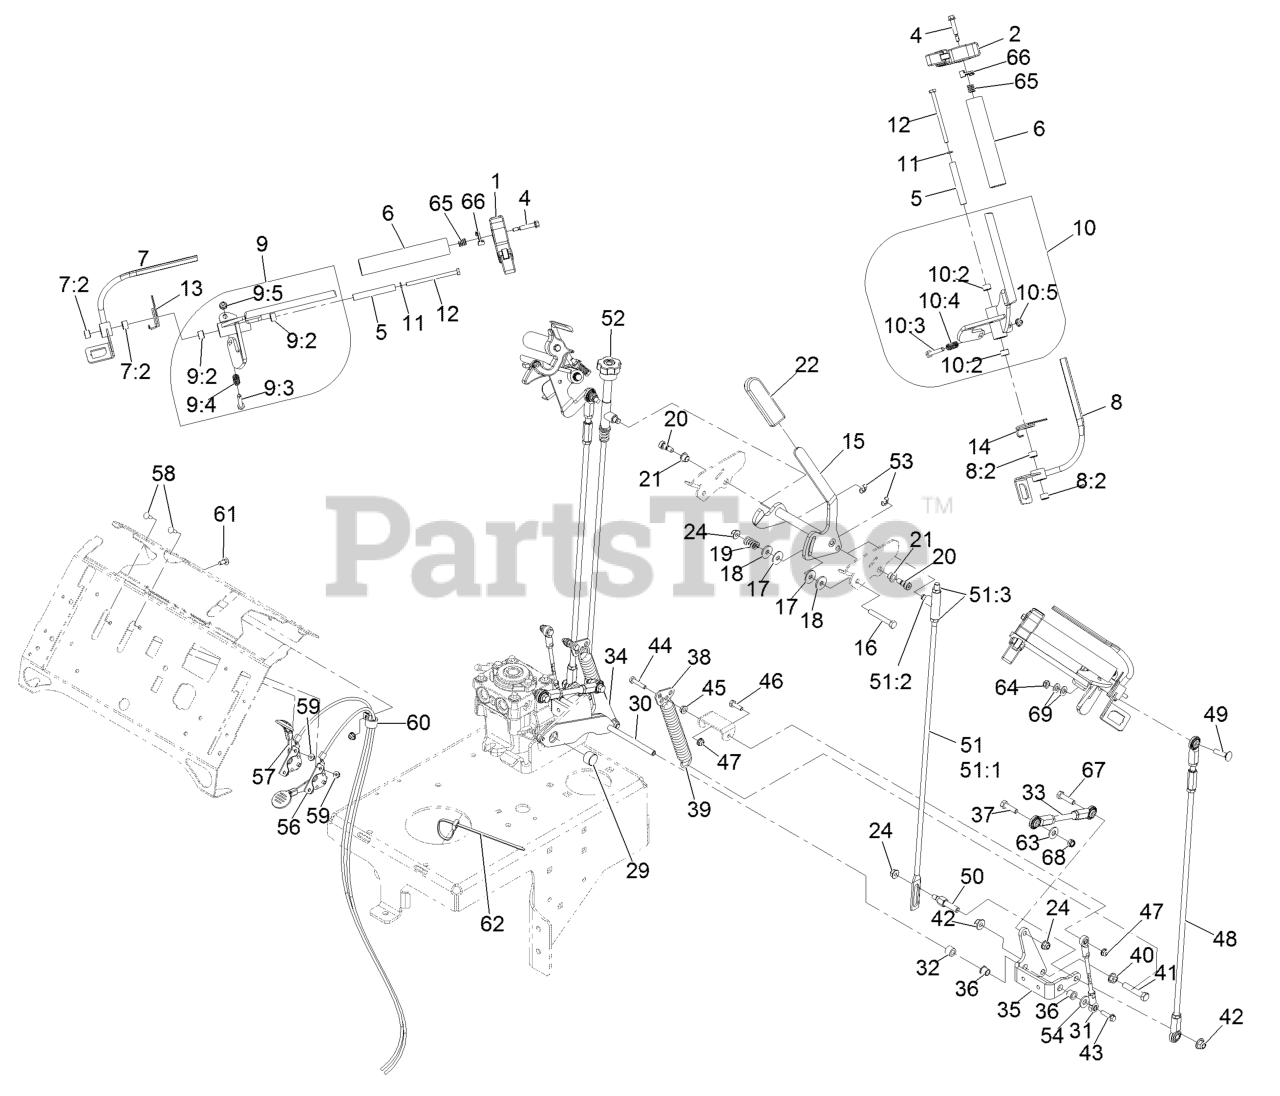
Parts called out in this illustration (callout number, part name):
1	ASM,LATCH RH THUMB
2	ASM,LATCH LH THUMB
4	SCREW-SHOULDER
6	GRIP-BAR, HANDLE
7	OPC-W/BUSHING, RH
7:2	BUSHING-SLEEVE
8	OPC-W/BUSHING, LH
8:2	BUSHING-SLEEVE
9	ASM, RT DRIVE LEVER
9:2	BUSHING-SLEEVE
9:3	SCREW-HH
9:4	SPRING, COMPRESSION
10	ASM, LT DRIVE LEVER
10:	BUSHING-SLEEVE
10:	SCREW-HH
10:	SPRING, COMPRESSION
11	SCREW-HH
12	SCREW-HH
13	SPRING, TORSION
14	SPRING, TORSION
15	SPEED CONTROL ASM
16	SCREW-HH
17	WASHER-FRICTION
18	WASHER-FRICTION
19	SPRING-COMPRESSION
20	SCREW-HSH
21	BUSHING
22	GRIP-HANDLE, STEERING
24	NUT-HF, NI
29	PIN-BELLCRANK LINK RETAIN
30	BELLCRANK LINK ASM
31	ASM, LINK
32	SPACER-WHEEL
33	ASM, MOTION LINK
34	BELLCRANK-LOWER, RT
35	BELLCRANK-LOWER, LT
36	BEARING
37	SCREW-HH
38	LINK, ADJUSTABLE
39	SPRING-EXTENSION
40	NUT-HHF, WHIZ
41	SCREW-HH
42	NUT-HF, NI
43	SCREW-HHF
44	SCREW-HH
46	SCREW-HH
48	ASM, MOTION LINK
49	Bolt-Carriage 5/16-18 X 1 1/4
50	STUD-CONTROL, SPEED
51	ASM, ROD LEFT
51:1	ROD, LEFT
51:3	NUT-HJ
52	ASM, ROD RIGHT
53	RING-RETAINING
54	WASHER-FRICTION
56	CONTROL-THROTTLE
57	CONTROL-CHOKE
58	BOLT-CARR
59	NUT-LOCK, FLANGE
60	CLAMP-CABLE
61	SCREW-CARR
62	TIE-CABLE
63	WASHER-FLAT
64	NUT-LOCK, NI
65	SPRING-TANK, FUEL
66	LATCH, ECS
67	SCREW-HH
68	Nut-5/16 Nyloc-Thin
69	WASHER-PLAIN
